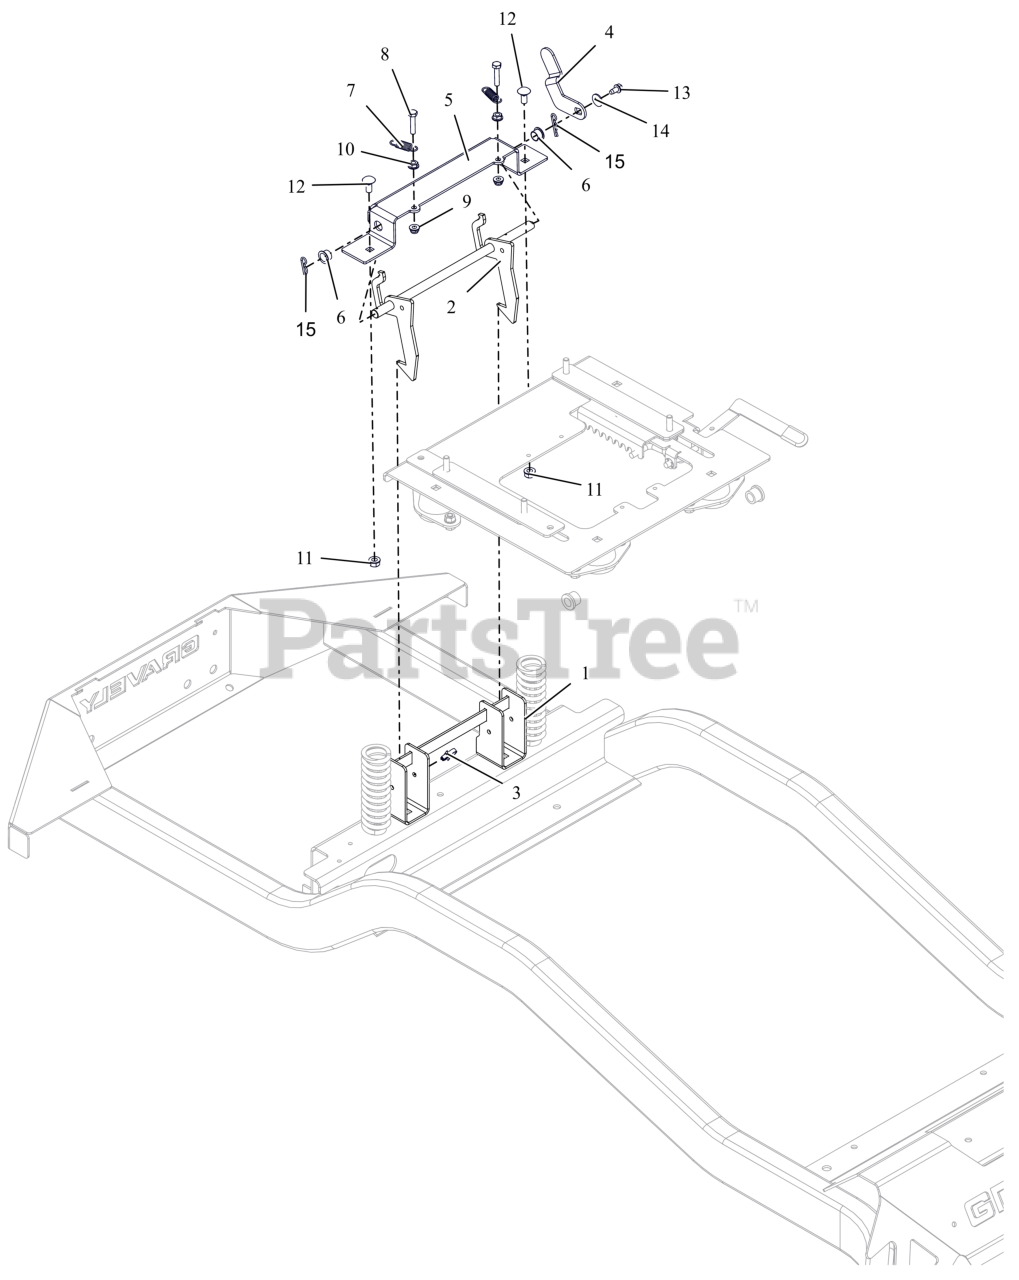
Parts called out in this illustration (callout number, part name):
1	WLDMT, LATCH RECEIVER
2	WLDMT, SEAT
3	ROUTING CLIP (1/2" ID)
4	LEVER, SEAT
5	BRKT, SEAT
6	BUSHING, POLYLINER-.50 SPLIT
7	SG-TENS .063X.44X1.56
8	BLT, HEX .25-20X1.25 G5 ZCC
9	NUT,NYL-FLG .25-20 GF ZCC
10	NUT-SPNLK-FLG .25-20 ZC120
11	NUT,LK-CTR-FLG .31-18 GF ZCC
12	BLT,RHSN .31-18X.75 G5 ZCC
13	SCR-TAP .25-20X.50 HWH ZCC
14	WSHR, FLT .312X.734X.065 ZCC
15	PIN, HAIR-INT .08X.38X1.42 ZCC
